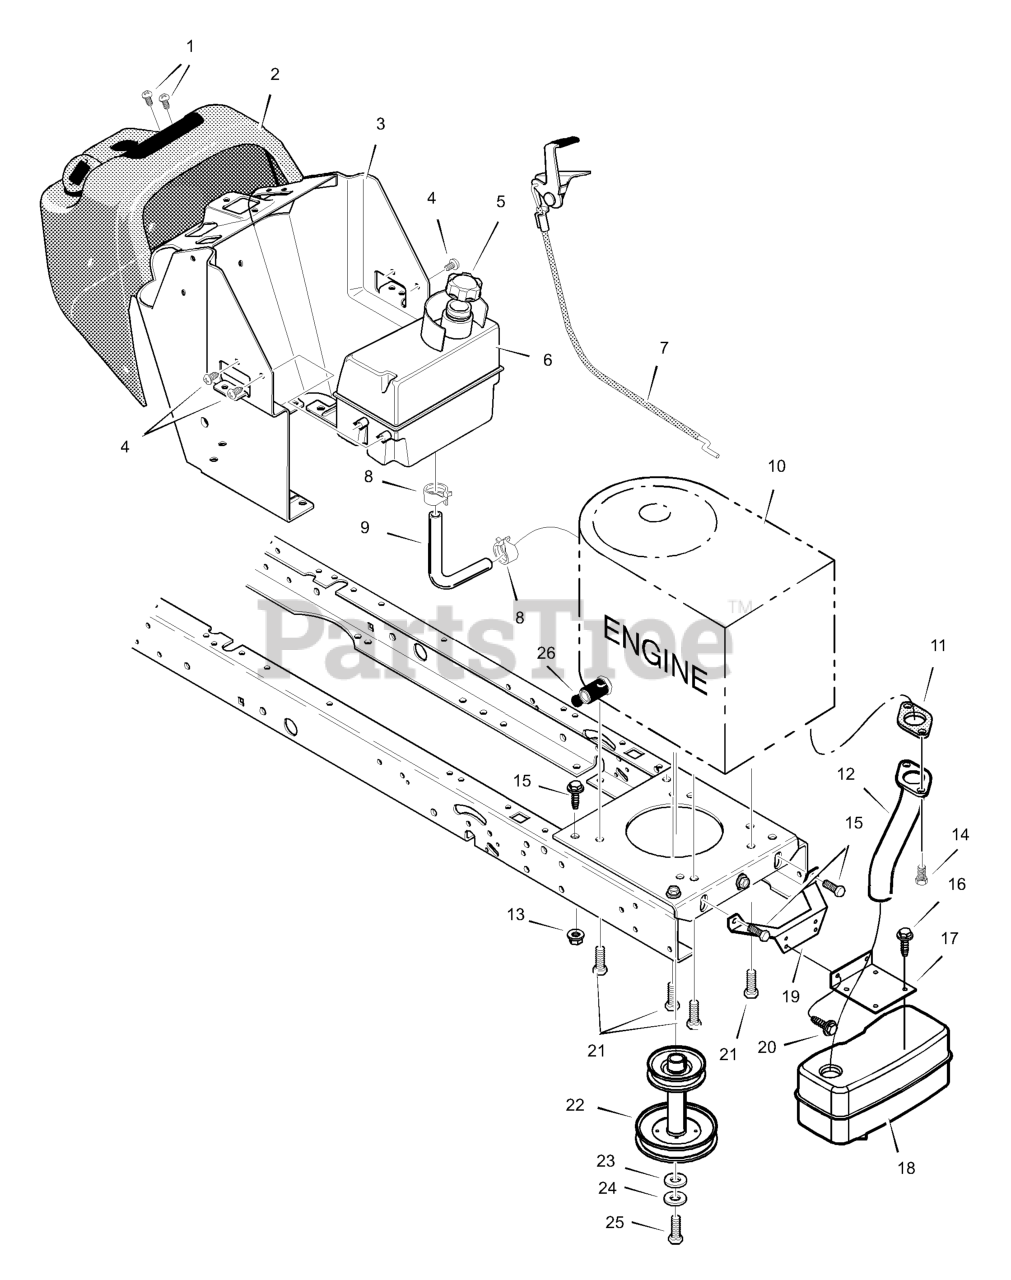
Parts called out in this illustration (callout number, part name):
1	Screw
5	Cap, Fuel
6	Tank, Fuel
7	Control, Throttle
8	Clamp, Hose
9	Line, Fuel
10	Engine *
11	Gasket, Exhaust
12	Tube, Exhaust
13	Nut
17	Bracket, Muffler
18	Muffler
19	Bracket, Muffler Mount
21	Bolt, Engine Mount
22	STACK PULLEY ASSEMBLY
24	Washer, Star
25	Bolt, Hex
26	Drain, Oil
